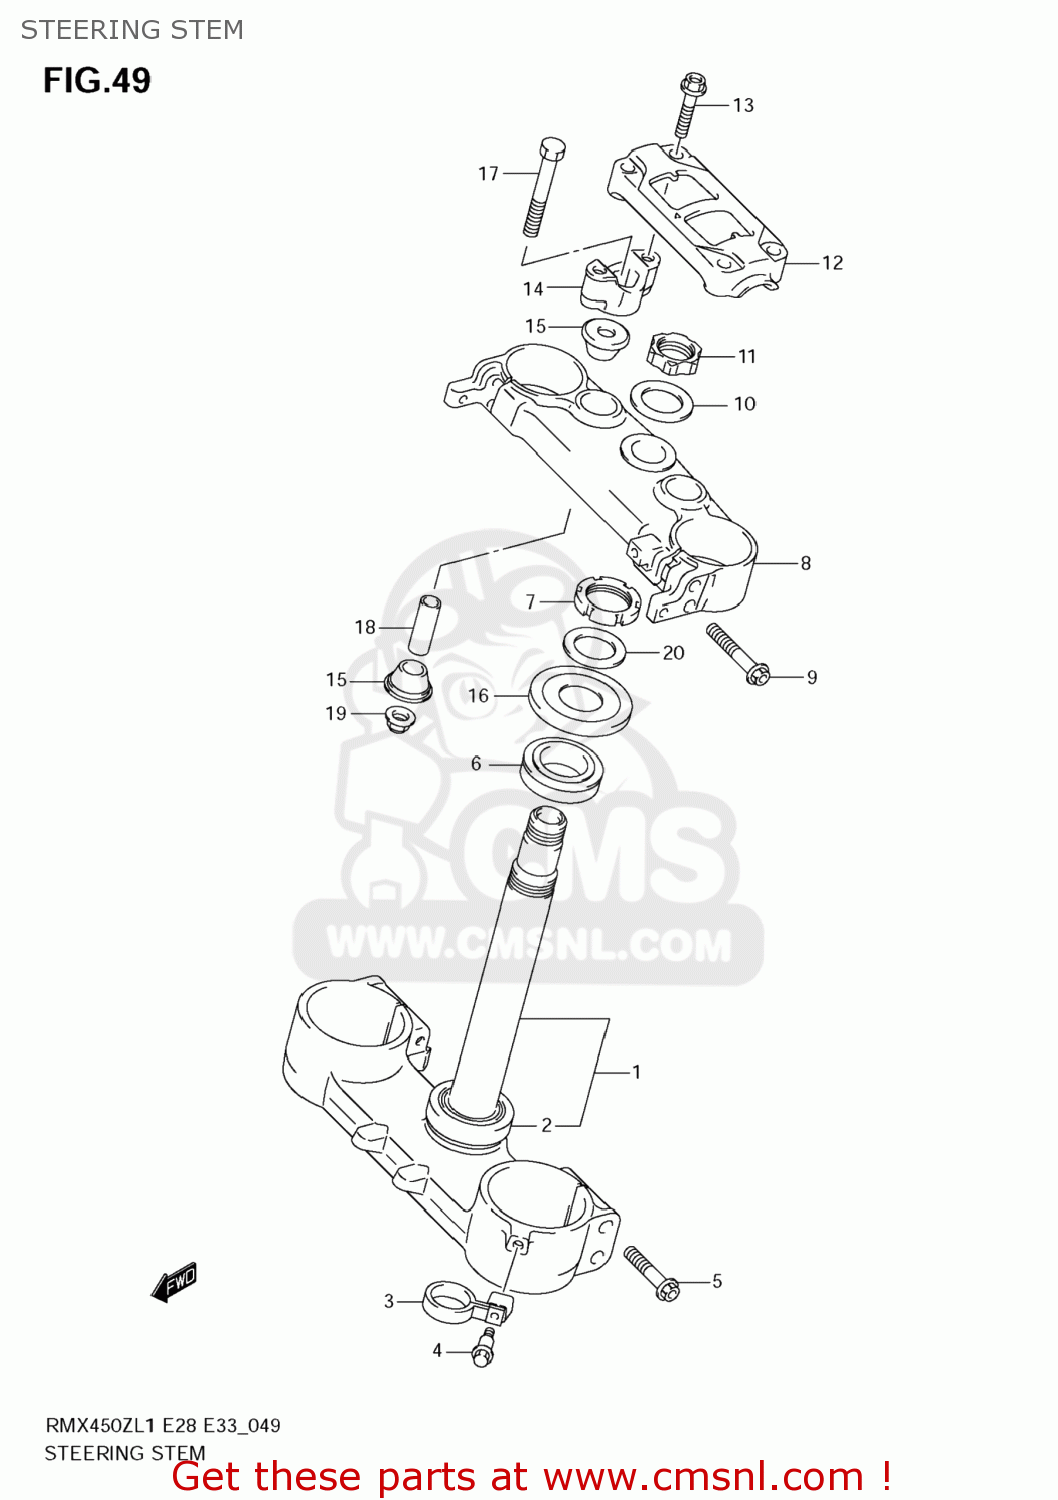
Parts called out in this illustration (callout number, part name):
1	STEM,STEERING
2	BEARING(30X52X16)
3	GUIDE,FR BRAKE HOSE
4	BOLT(6X20.5)
5	BOLT
6	BEARING(30X52X16)
7	NUT,STEERING
8	HEAD,STEERING STEM
9	BOLT
10	WASHER,STEM HEAD
11	NUT,STEM HEAD
12	HOLDER,HANDLE
13	BOLT
14	HOLDER,HANDLE
15	CUSHION,RUBBER
16	SEAL,STEERING UPR DUST
17	BOLT,HANDLE HOLDER
18	SPACER
19	NUT
20	WASHER
